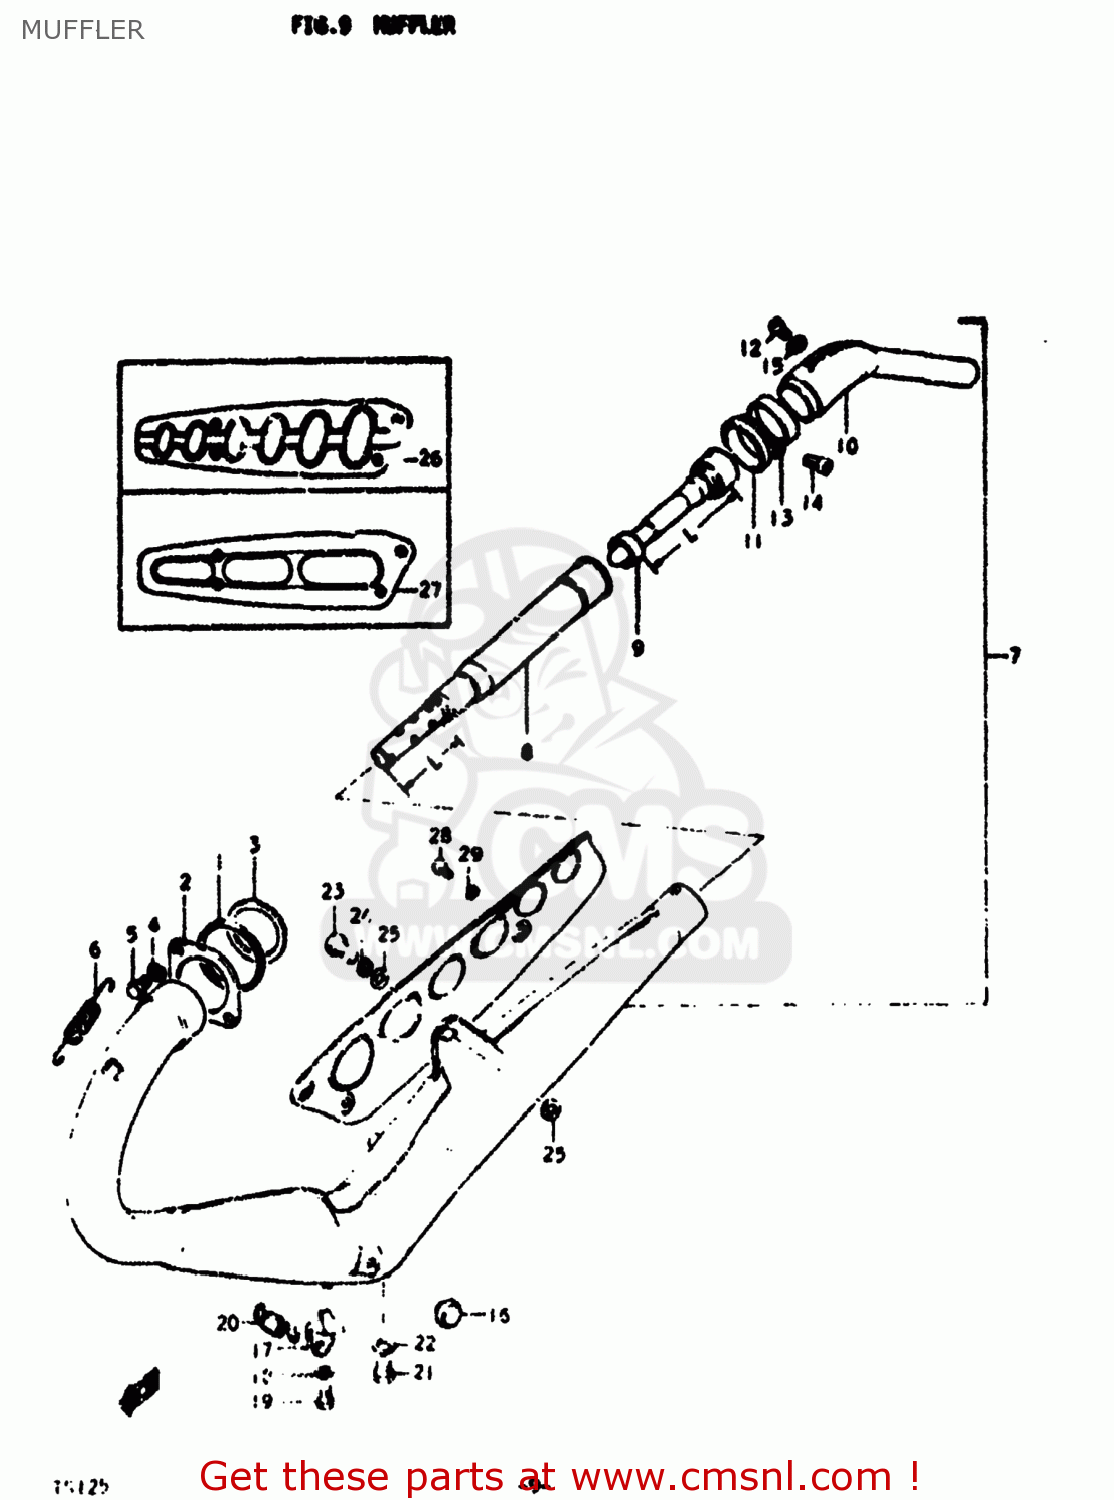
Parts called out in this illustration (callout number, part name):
1	GASKET,EXHAUST PIPE (NAS)
2	CLAMP, EXHAUST PIPE
3	CUSHION,EXHAUST PIPE
4	LOCK WASHER
5	BOLT
6	SPRING
7	MUFFLER ASSEMBLY
8	ARRESTER,SPARK
9	TUBE,MUFFLER CLEAN OUT
10	EXHAUST EXTENSION
11	GASKET,MUFFLER TAIL PIPE (NAS)
12	SCREW
13	CLAMP
14	SCREW
15	GASKET
16	CUSHION(11.5X22X20)
17	BRACKET, MUFFLER STOPPER
18	LOCK WASHER
19	BOLT
20	SPRING
21	BOLT 10X9
22	GASKET(10X14X3.6) (NAS)
23	BOLT
24	LOCK WASHER
25	WASHER
26	COVER,MUFFLER
27	COVER,MUFFLER
28	SCREW
29	LOCK WASHER
